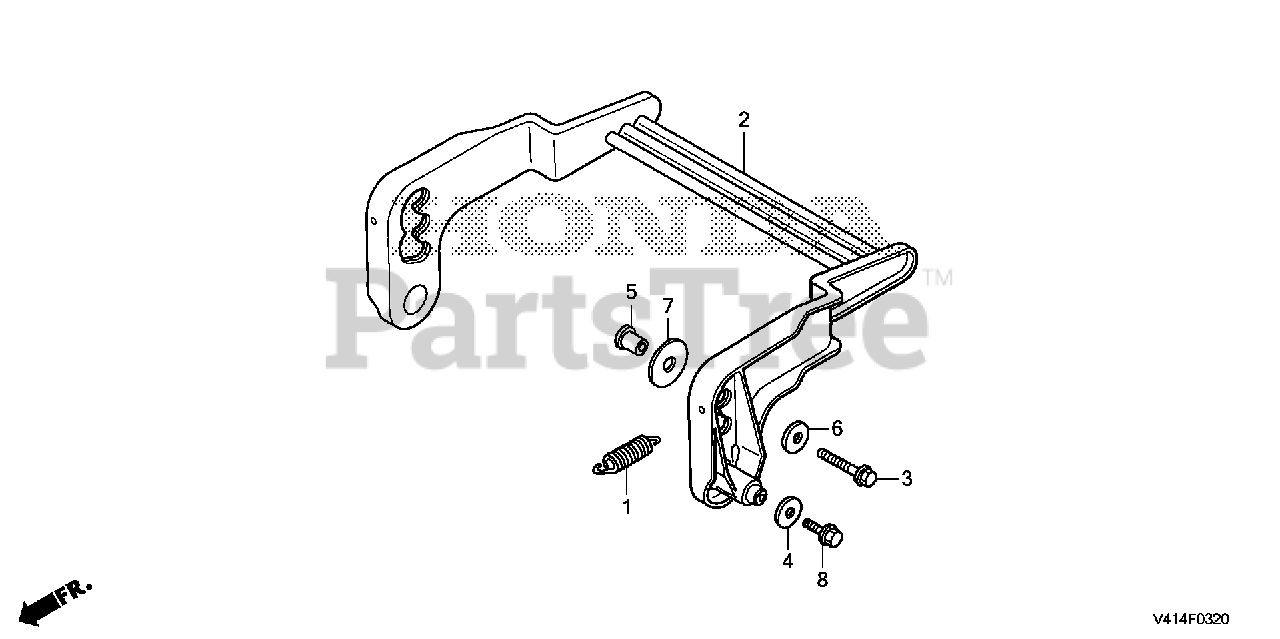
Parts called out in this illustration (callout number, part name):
1	SPRING, HEIGHT ADJUSTING
2	PLATE, HEIGHT ADJUSTING
3	BOLT, FLANGE (8X30)
4	WASHER, PLAIN (8X23X3.2)
5	COLLAR, HEIGHT ADJUSTING
6	WASHER, PLAIN (8MM)
7	WASHER, PLAIN (12MM)
8	BOLT, FLANGE (8X14)
